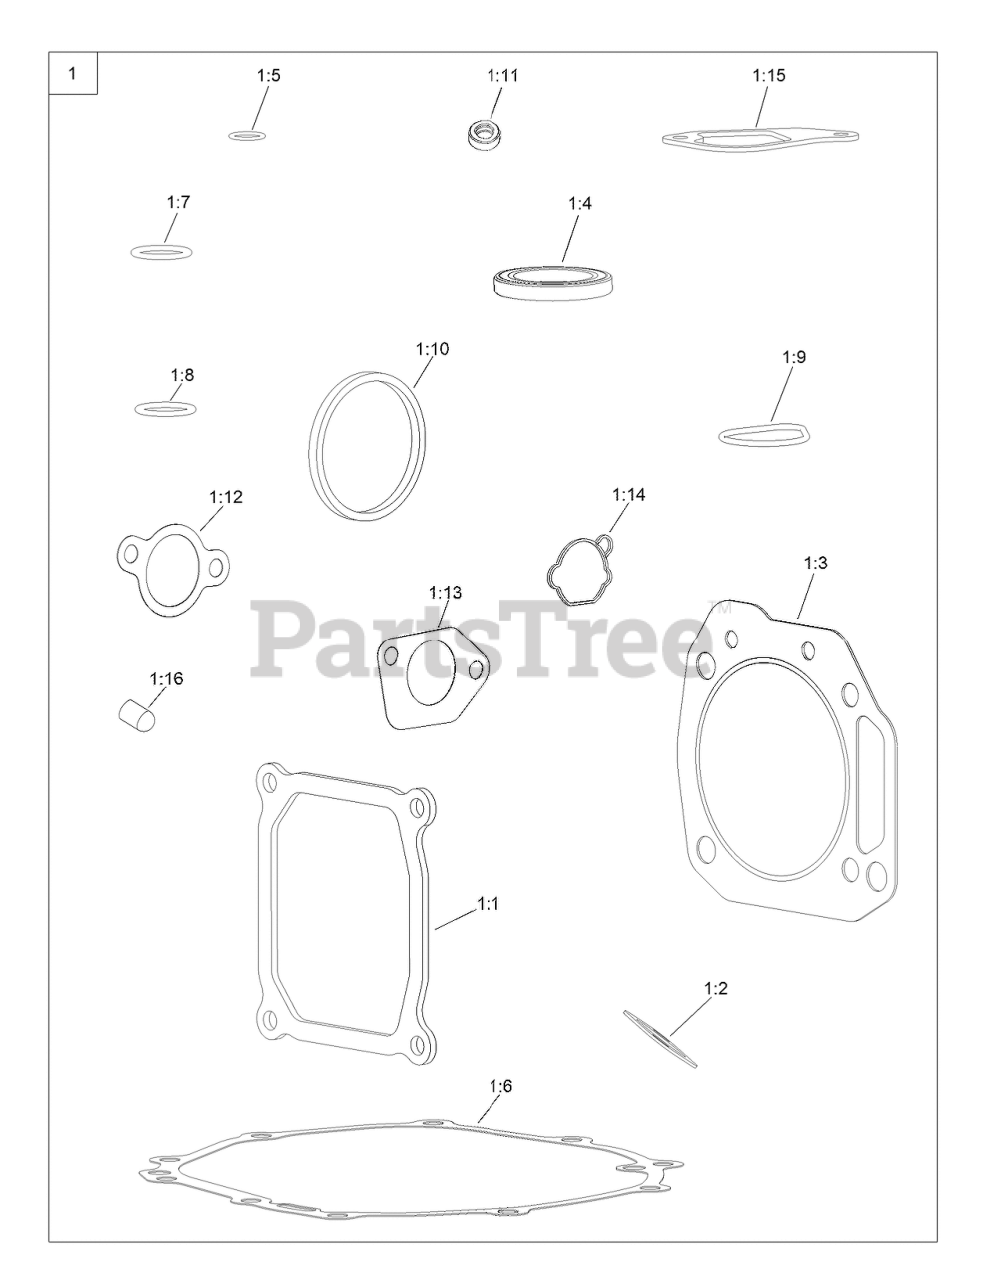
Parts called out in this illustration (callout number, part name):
1	GASKET AND SEAL KIT
1:1	GASKET-COVER, VALVE
1:2	GASKET-EXHAUST
1:3	GASKET-CYCLINDER
1:4	SEAL-OIL
1:5	O-RING
1:6	GASKET-CRANKCASE
1:7	O-RING
1:8	O-RING
1:9	SEAL-PUMP, OIL
1:10	SEAL-ADAPTOR, OIL
1:11	SEAL-OIL
1:12	GASKET-CARBURETOR
1:13	GASKET-CARBURETOR
1:14	GASKET-CARBURETOR
1:15	GASKET-BREATHER
1:16	CAP-SEAL
